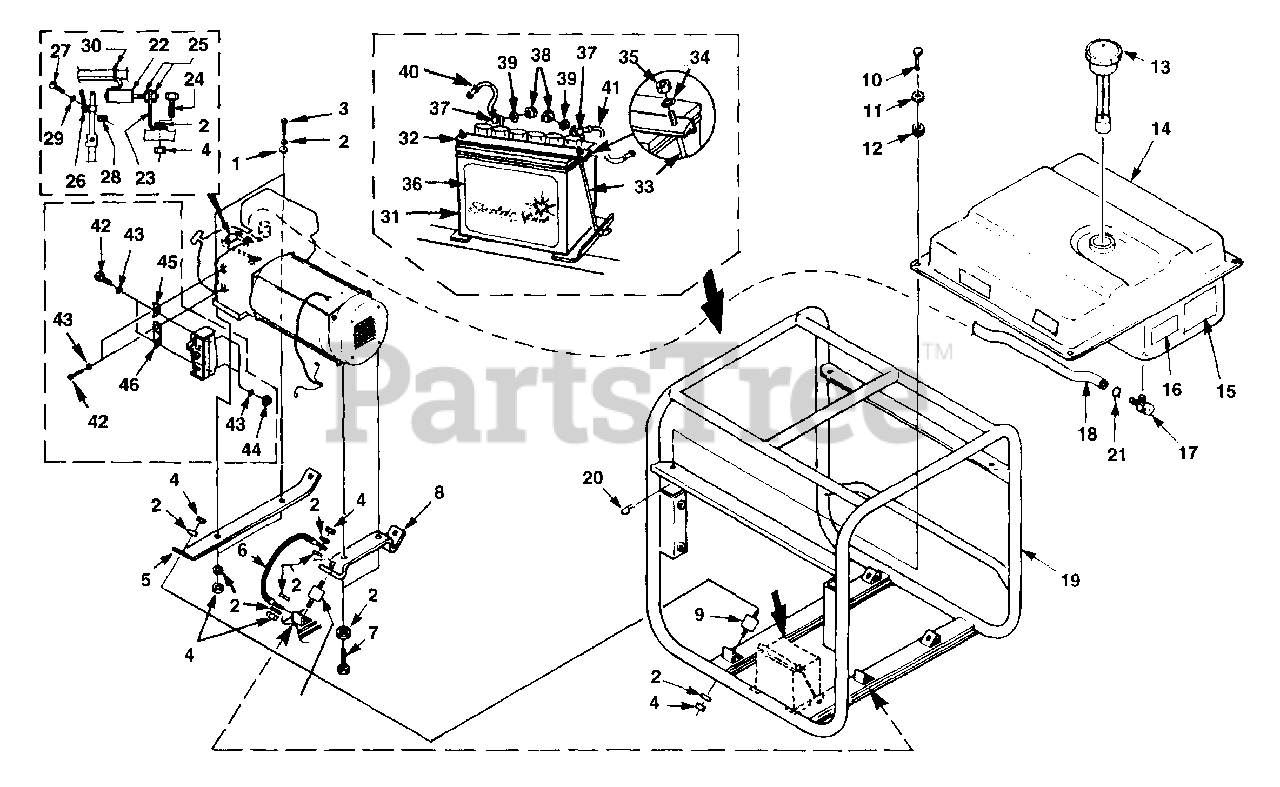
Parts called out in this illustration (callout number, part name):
1	WASHER-Flat (5/16)
2	WASHER-Lock/Int.
3	SCREW-Cap Hex Hd. (5/16-18 x 2")
4	NUT-Hex (5/16-18)
5	SUPPORT-Engine
6	GROUND-Strap
7	SCREW-Thread Form. (5/16-18 X 1")
8	SUPPORT-Generator
9	ISOLATOR-Vibration
10	PIN-Clevis
11	WASHER-Flat
12	GROMMET-Isolator
13	CAP-Fuel
14	TANK-Fuel
15	DECAL-Caution
16	DECAL-Fuel Valve
17	VALVE-Fuel
18	FUEL-Line
19	ROLL CAGE
20	PIN-Cotter Hair
21	HOSE-Clip
22	ELECTROMAGNET
23	BRACKET-Magnet, 11HP
24	SCREW-Cap Hex Hd. (5/16-18 X 1")
25	NUT-Hex
26	PADDLE-8HP & 11HP
27	SCREW-Machine Pan Hd. (8-32 X 3/8")
28	NUT-Speed
29	WASHER-Lock/Int.
30	TIE-Cable
31	BATTERY-12 Volt
32	STRAP-Battery
33	BOLT-Battery
34	WASHER Lock
35	NUT-Hex (#10)
36	DECAL-Electric Start
37	SCREW-Cap Hex Hd. (1/4-20 X 5/8")
38	NUT-Hex
39	WASHER-Lock
40	CABLE-Battery (Pos.)
41	CABLE-Battery (Neg.)
42	SCREW-Cap Hex Hd. (1/4-20 X 5/8")
43	WASHER-Lock (Int.) (1/4")
44	NUT-Hex (1/4-20)
45	BRACKET-Panel/Engine
46	BRACKET-Panel/Engine
